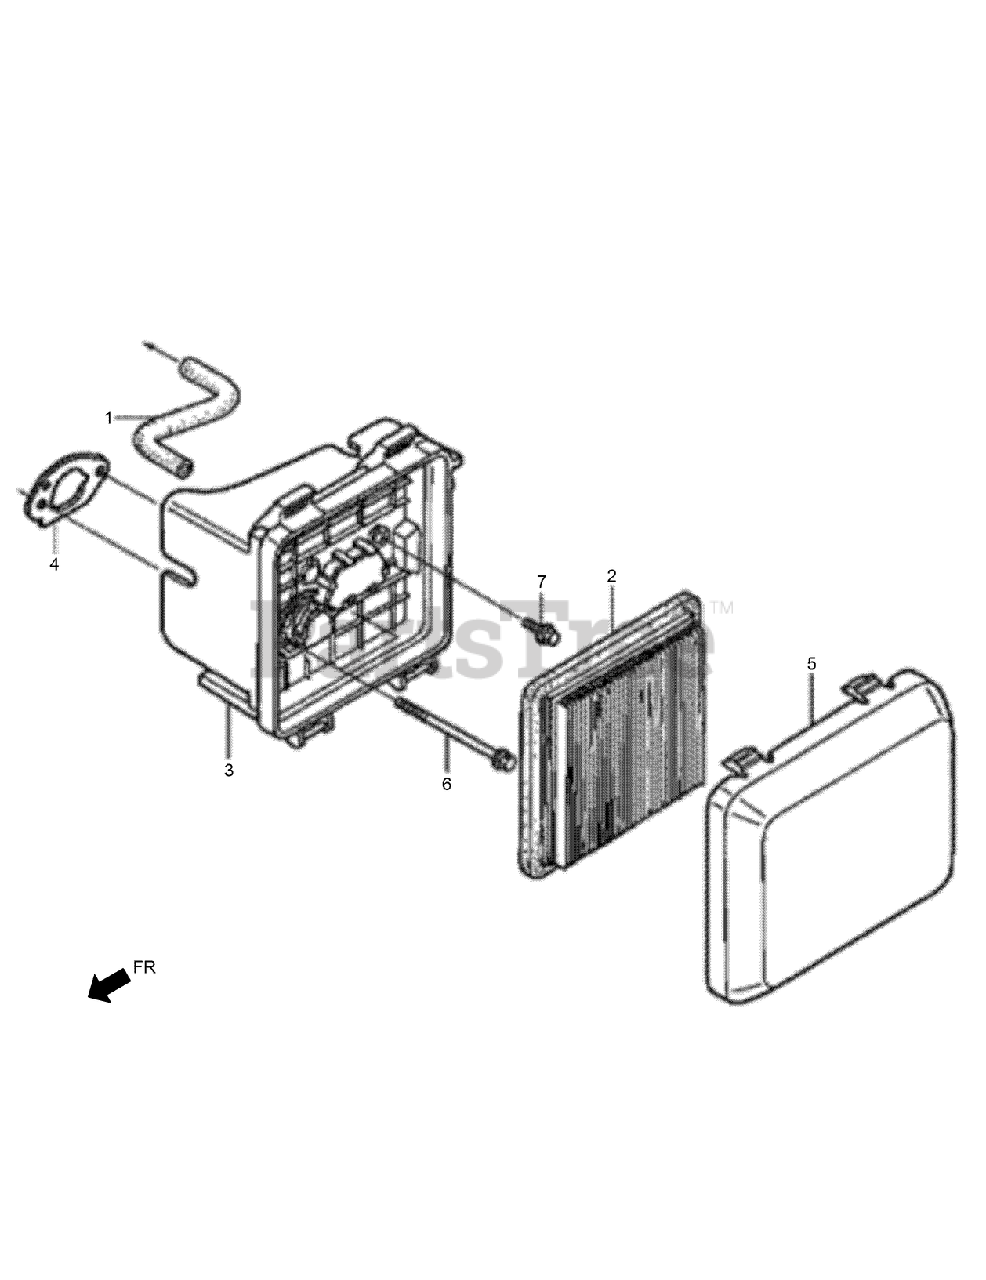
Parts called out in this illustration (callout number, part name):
1	TUBE-BREATHER
2	ELEMENT-AIR CLEANER
3	CASE ASM-AIR CLEANER
4	PACKING-AIR CLEANER
5	COVER-AIR CLEANER
6	BOLT-FLANGE-6X86
6	BOLT-FLANGE-6X85
7	BOLT-FLANGE-6X14
